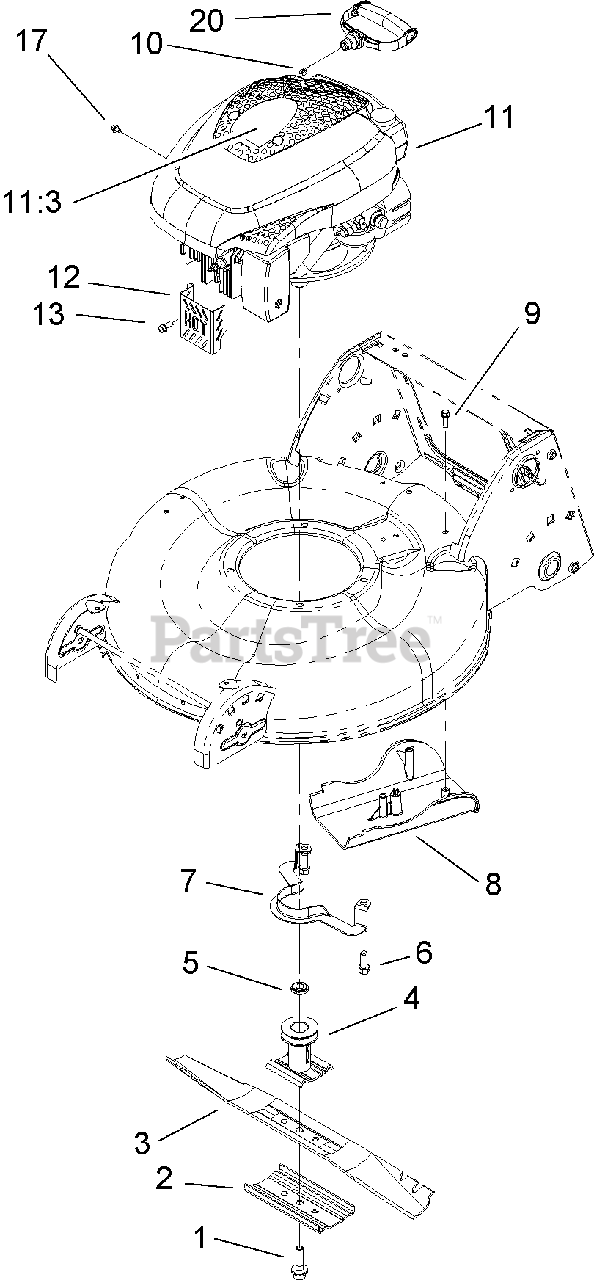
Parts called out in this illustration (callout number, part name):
1	BOLT-BLADE
2	SUPPORT-BLADE
3	BLADE-21 INCH
4	BLADE DRIVER ASM
5	Spacer-Driver
6	SCREW
8	COVER-BELT
9	SCREW-HWH
10	STOP-ROPE
11:3	DECAL-RECOIL
12	GUARD-MUFFLER
13	SCREW-HWH
17	SCREW-HWH
20	HANDLE-RECOIL
